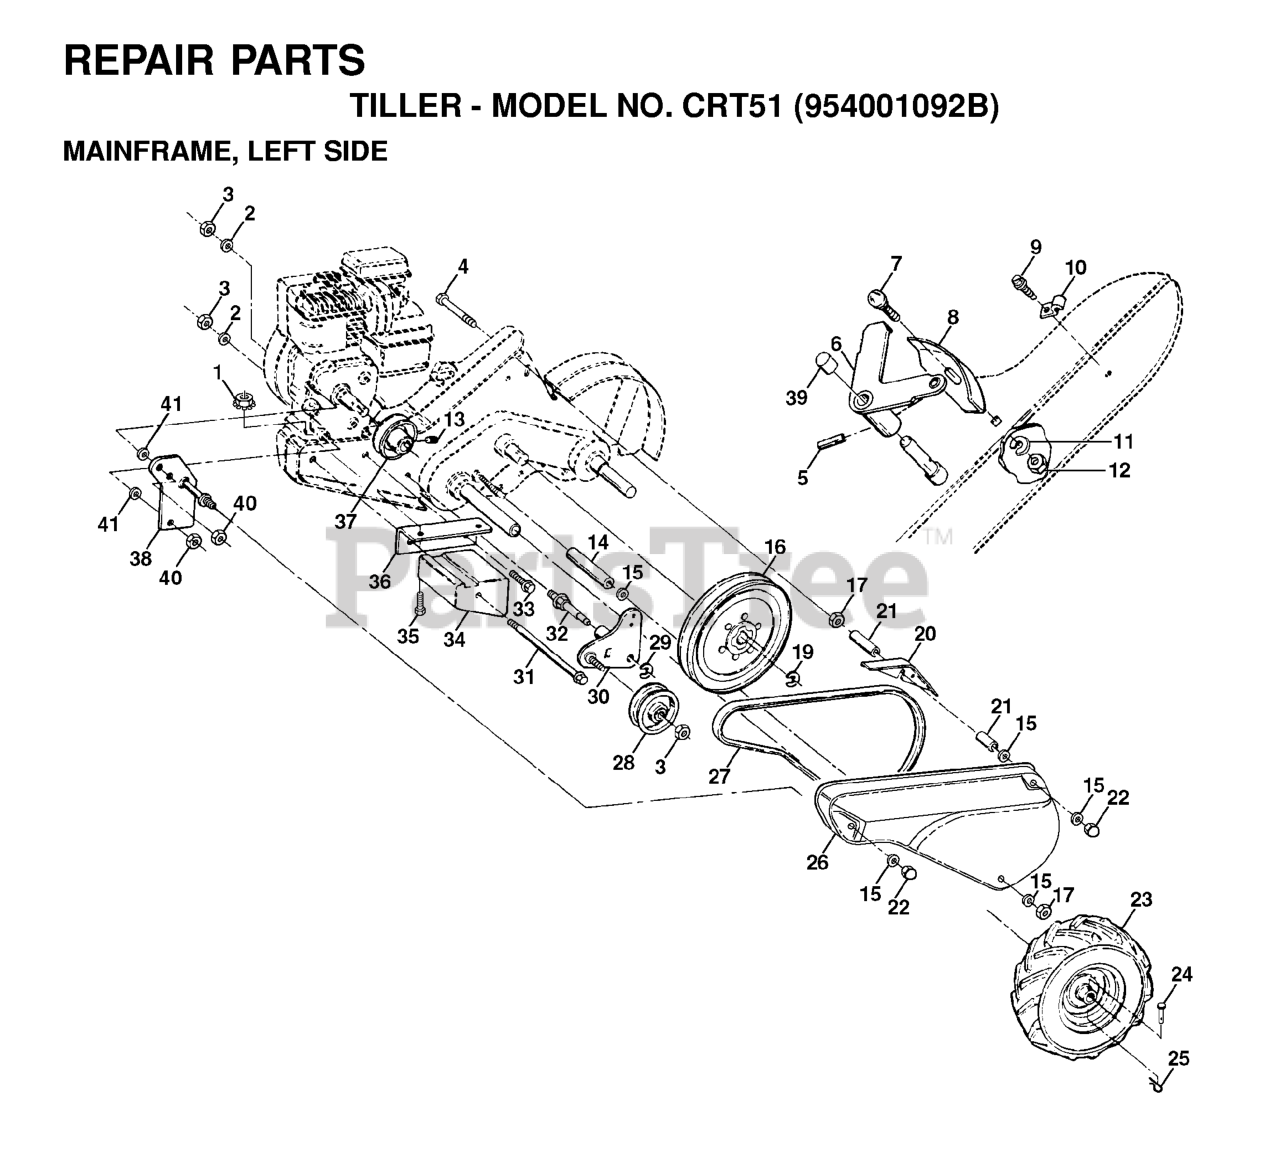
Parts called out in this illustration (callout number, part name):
1	CYLINDER.HEAD.ASM.W/GASKET.254
2	KIT.PUSH.ROD.&.PLATE.W/VC.GASK
3	COVER.VALVE.W/GASKET.254CC
4	CYLINDER LCT 254 FT OIL DRAIN
5	PISTON.&.ROD ASSEM.254CC
7	CAMSHAFT.MCR.W/GASKET.254CC
8	FLYWHEEL.ELEC.STRT.(8.MAGNETS)
9	FLYWHEEL FAN 420586
10	CRANKSHAFT.KEYED(#18).SNOW.254
13	MUFFLER.ASSEM.GEN2.SNOW.254CC
14	FUEL.TANK.SNOW.2.7L.BLACK.254C
15	FUEL.PETCOCK.SNOW(SKSN4900)
16	FUEL CAP OVERSIZED CLICK STYLE
17	CARBURETTOR LCT 254 W/IDLEDOWN
18	COIL.ING.CDI.HI TEMP.SKSNO416.
20	PLUG.SPARK.PLAT.SKSN2404.1
21	SWITCH.ON/OFF(SKSN-0403)
22	SHIELD.FLYWHEEL.ELEC.STRT.208C
23	FUEL HOSE KIT
24	BRACKET.SPEED.CNTRL.FIXED.254C
25	GOVENOR.GEARS ASM(SK2082900)
26	KIT.GOVERNOR.ARM.&.LINK.254CC
27	KIT.GOVERNOR.CRANK(SK208-3100)
28	RECOIL.STRT.ROUND(BLK) SNOW
29	STRTER.CUP(NON-SLOT)SKSN0601.2
30	BLOWER HSG.LCT 254 GLOSS BLK S
31	CRANKCASE.CVR.PRESS.IN.HI-OIL.
32	KIT.SEAL.OIL.2.PIECES.254CC
34	SPARK.PLUG.BOOT.SNW,SKSN4691.1
35	ELEC.START.GEN2.SKSN0451.1
36	KIT.ENGINE.GASKET.254CC
38	KIT.ROCKER.ARM.W/GASKET.254CC
39	CHOKE.KNOW.SNOW(SKSN4500)
40	NON REMOVABLE PLUG
43	TUBE.BREATHER.LCT.208
47	TUBE ASSY HIGH OIL-FILL
48	WIRE.HARNESS.SNOW
49	KIT.OIL.DRAIN.PLUG(SK2089911
50	KIT.HEATER.BOX.SNOW.254CC
52	PRIMER.BULB.WITH HOSE (SNOW)
53	SWITH.KEY.ASSEM.SNOW.SINGLE.ST
54	KEY SET(2 KEYS) SKSN0407.1
55	OIL PIPE DRAIN LCT 254
56	SHIELD.CARBURETOR.VAPOR
58	SHIELD.GOVERNOR.LINKAGE.254CC
59	FUEL TANK SKIRT SHIELD LCT 254
60	208CC 60W ALTERNATOR
61	FUEL KNOB-SNOW
62	HANDLE.RECOIL.DELUXE.LCT
65	TAPPET.KIT.LCT.208CC
69	CARB.STUDS & COUPLING KIT.SNOW
70	CARB.REPAIR.KIT.LCT.SK9900.2
74	COVER.MUFFLER.HEAT.SHIELD.
77	BOLT.KIT.RECOIL.LCT.ALL.ENGINE
79	COVER.CARBURETOR.SNOW
80	SHIELD.GOVERNOR.LINK.SNOW.254C
81	KEYS.FLYWHEEL.136/291CC.5PACK
82	SPACER.CARBURETOR.208CC.LCT
85	STRAINER.FUEL.TANK.LCT.208CC
86	KIT.BOLT.CYLINDER.HEAD.(4PC)
87	KIT.BOLT.CRANKCASE.COVER.6PC
88	STUD.MUFFLER.KIT.LCT
89	KNOB LCT.SKSN5325.1 SPEED
9999	JET HIGH ALTITUDE LCT 5000 25
